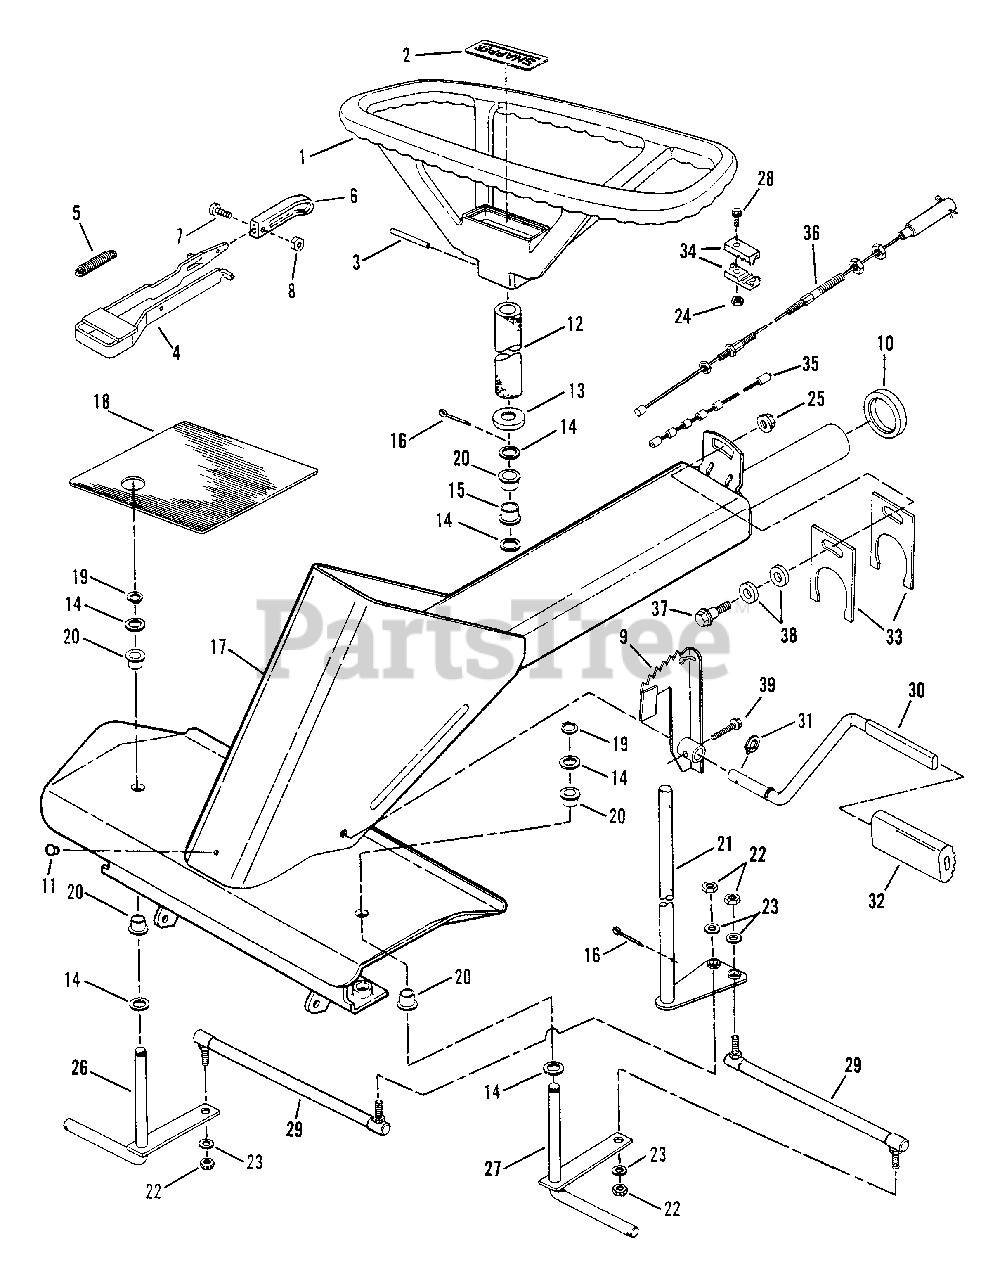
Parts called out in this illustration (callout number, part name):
1	ASSEMBLY, Steering Wheel
2	DECAL, Snapper
3	PIN, 1/4 x 1-1/2" Roll
4	BRACKET, Clutch/Brake
5	SPRING
6	KNOB
7	SCREW, #8-32 x 3/8" Cross Recess
8	NUT, #8-32 Hex
9	ARM, Clutch/Brake
10	SPACER, Main Tube
11	PLUG
12	COVER, Steering Shaft (Foam)
13	COVER
14	WASHER, 3/4 Flat
15	BUSHING, 3/4" Steering Shaft
16	PIN, 3/16 x 1-1/2" Cotter
17	FRAME, Front (42" Models)
18	PAD, Foot (Right Side Shown) (42" Models)
19	RING, Retaining
20	BEARING
21	SHAFT, Steering (Wide Front End)
22	NUT, 5/16-24 Hex
23	WASHER, 5/16 Split Lock
24	NUT, 1/4-20 Hex Center Lock
25	NUT, 3/8-24 Hex Flange Lock
26	PIN, Wide King (Right Side)
27	PIN, Wide King (Left Side)
28	BOLT, 1/4-20 x 3/4" Hex Flange Lock
29	TIE-ROD (42" Models)
30	PEDAL, Clutch/Brake
31	RING, 5/8" External Retaining
32	PAD, Clutch/Brake Pedal
33	SPACER, Pivot
34	UNION, Cable
35	CABLE, Clutch
36	CABLE, Brake
37	BOLT, 3/8-24 x 5/8" Hex Shoulder
38	SPACER
39	SCREW, 5/16-18 x 1-1/4" Self-Tapping
